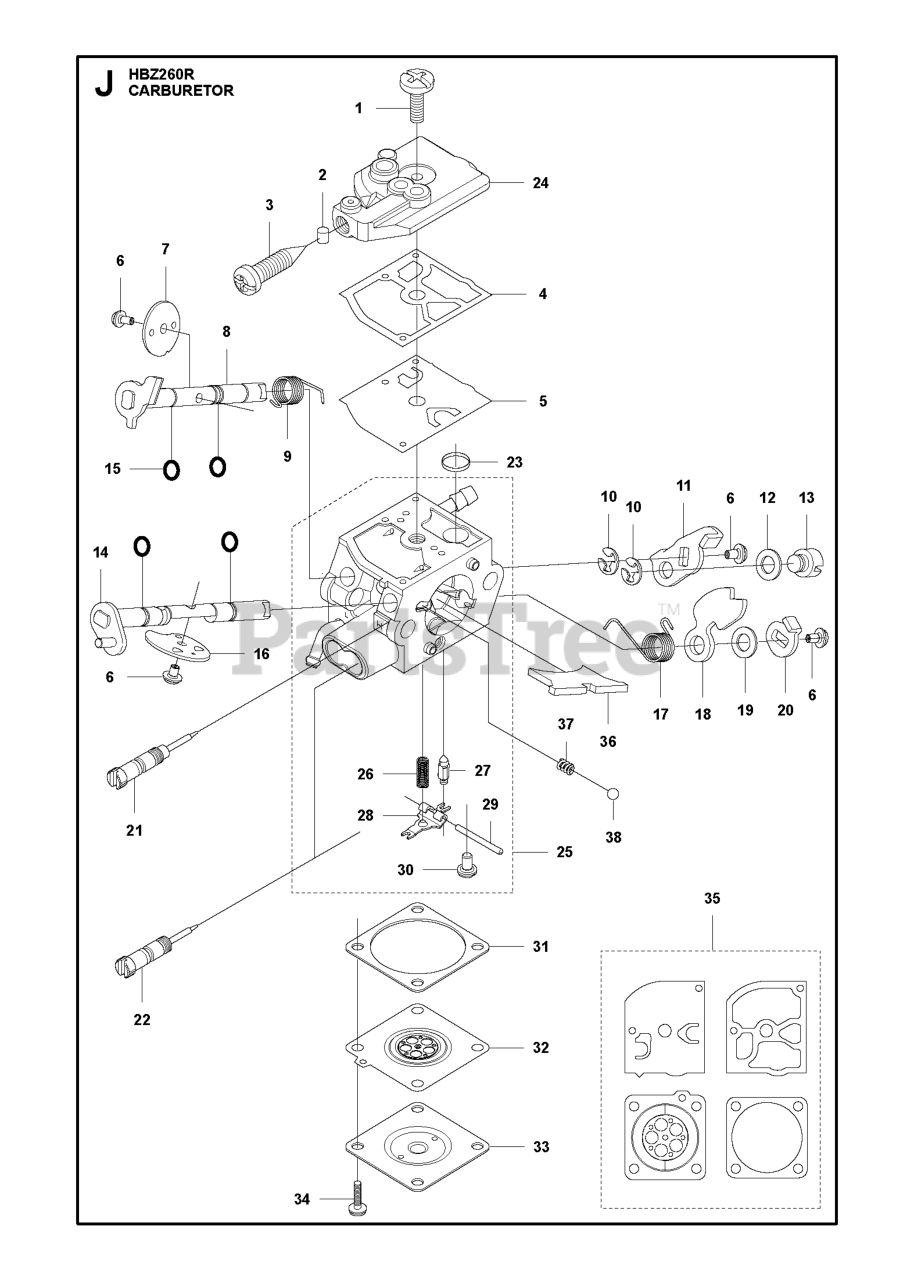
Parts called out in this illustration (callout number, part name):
4	GASKET PUMP
5	DIAPHRAGM PUMP
7	VALVE THROTTLE
8	SHAFT ASSY THROTTLE
9	SPRING THROTTLE RETURN
14	SHAFT ASSY CHOKE
17	SPRING RETURN
21	SCREW IDLE MIXTURE H225-0007B
23	STRAINER
24	PUMP COVER
27	VALVE INLET
30	SCREW M3X6
31	GASKET METERING CHAMBER
32	DIAPHRAGM ASSY METERING
33	COVER METERING CHAMBER
34	SCREW M3X7
35	GASKET KIT
36	PLATE SPLIT
37	SPRING FRICTION
38	BALL STEEL
